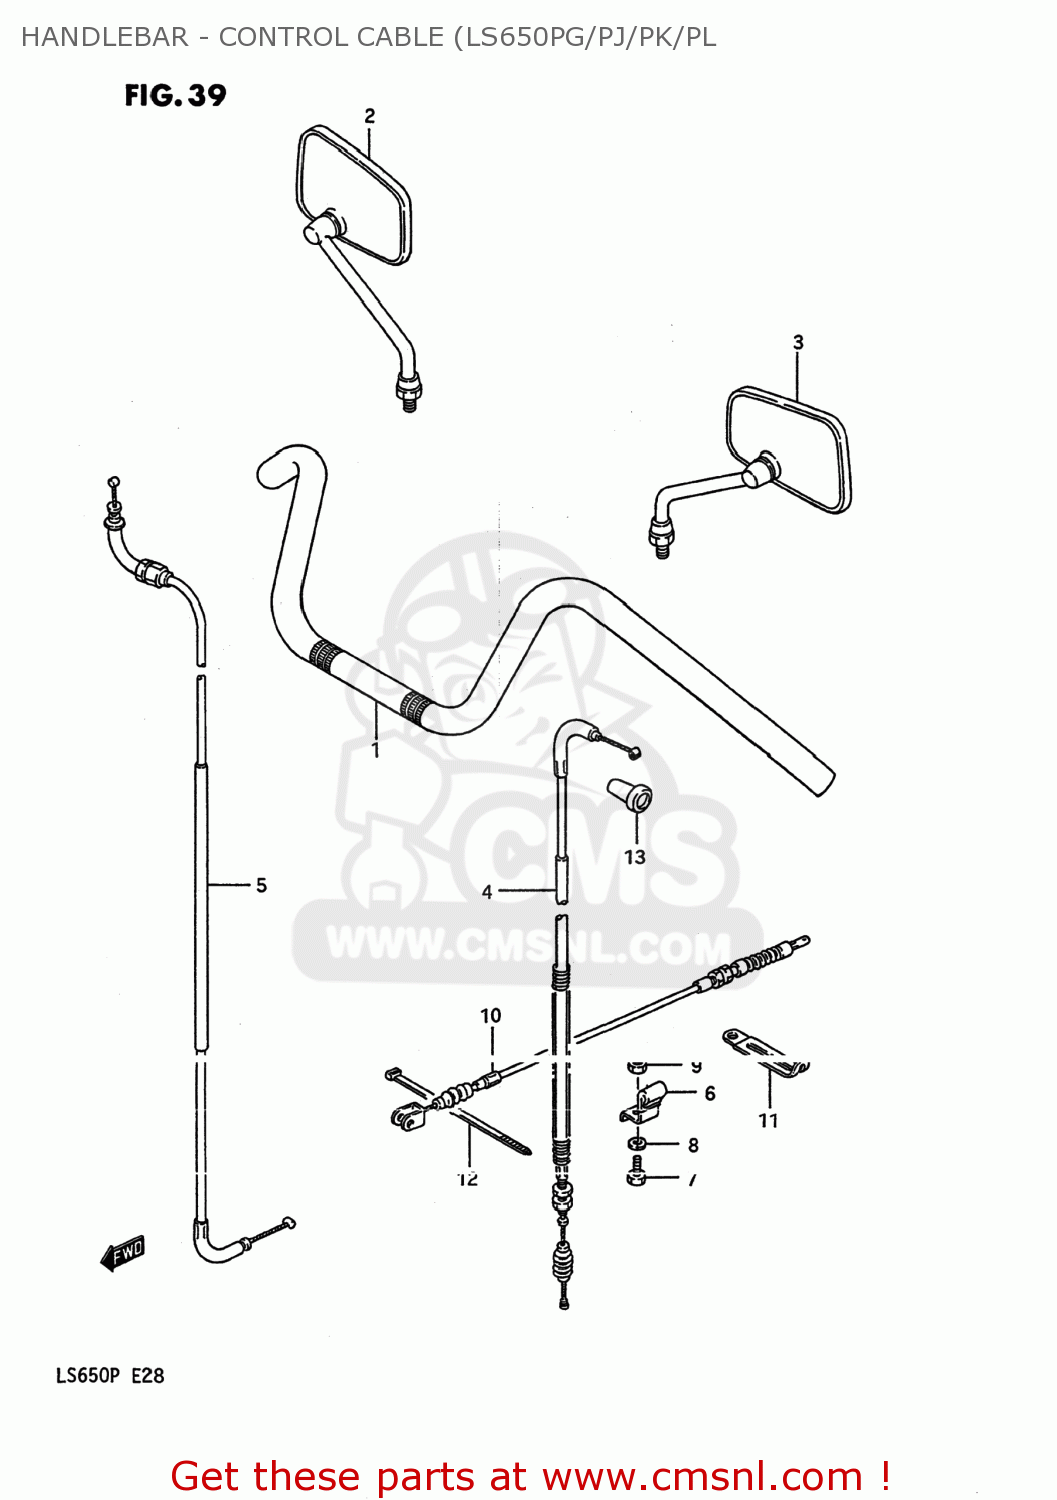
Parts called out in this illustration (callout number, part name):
1	HANDLEBAR
2	MIRROR ASSEMBLY,REAR VIEW
3	MIRROR ASSEMBLY,REAR VIEW
4	CABLE ASSY,CLUTCH
5	CABLE ASSY,THROTTLE
6	GUIDE,CABLE
7	BOLT
8	WASHER,LOCK
9	NUT
10	CABLE COMP,STOP LAMP SWITCH
11	CLAMP
12	CLAMP
13	BOOT,CLUTCH CABLE
